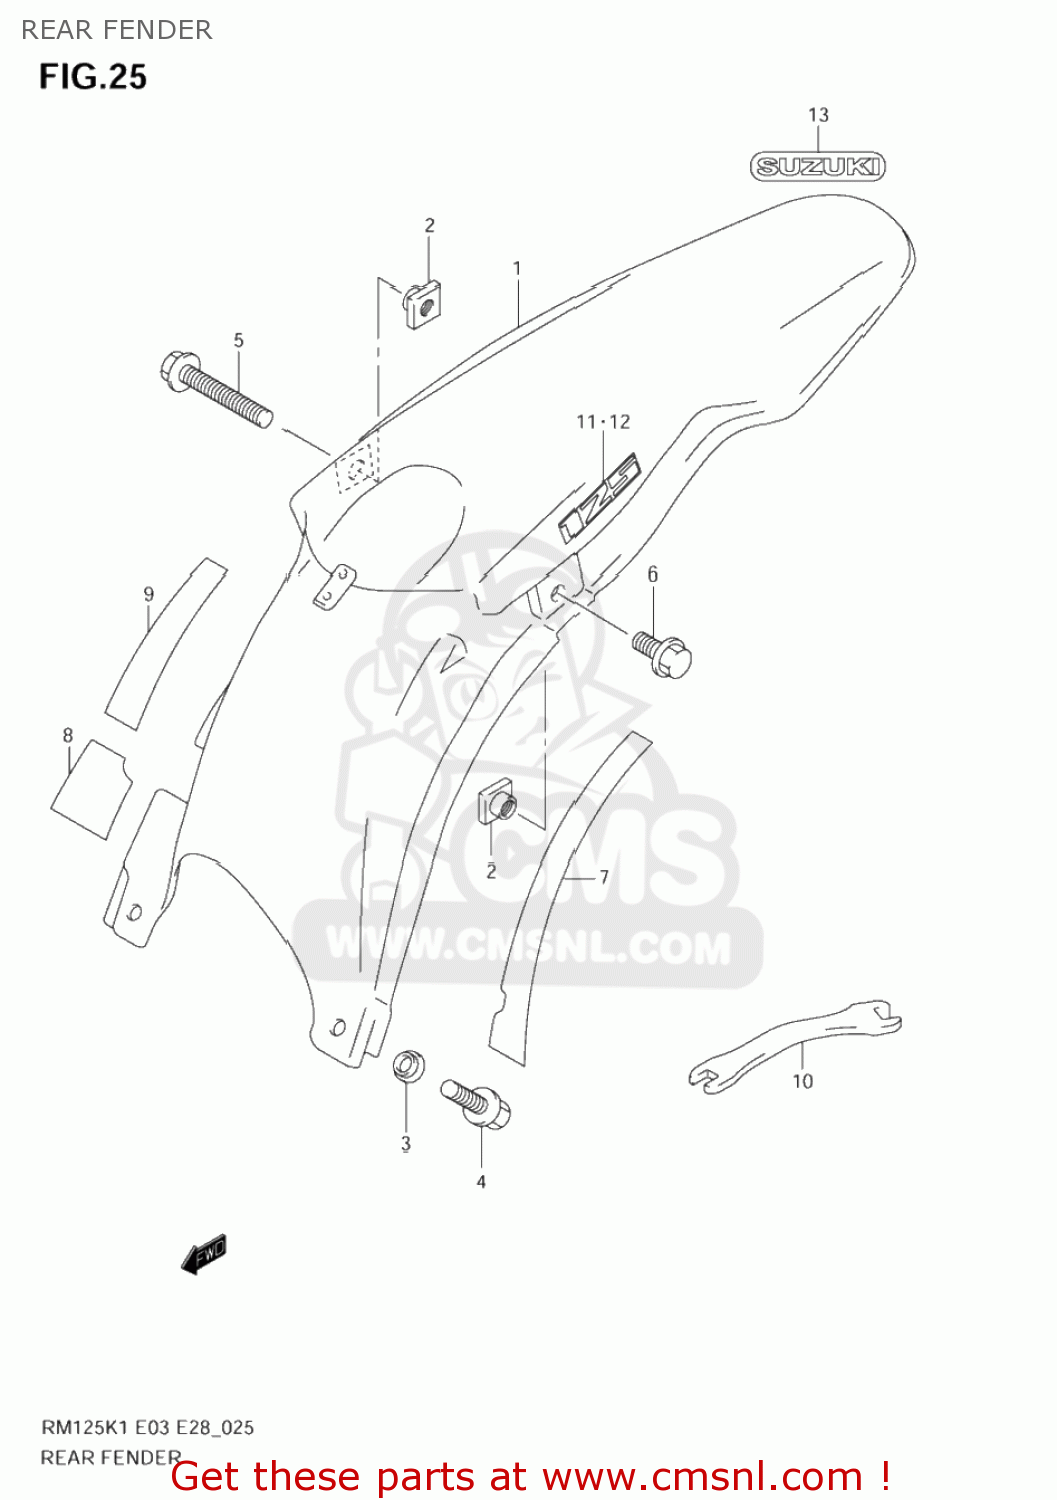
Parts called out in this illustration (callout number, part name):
1	FENDER,RR
2	NUT
3	WASHER
4	SCREW
5	BOLT
6	BOLT
7	CUSHION,RR FENDER NO.1
8	CUSHION,RR FENDER NO.2
9	CUSHION,RR FENDER NO.3
10	SPANNER,OPEN
11	TAPE,RR FENDER,R
12	TAPE,RR FENDER,L
13	EMBLEM,RR
